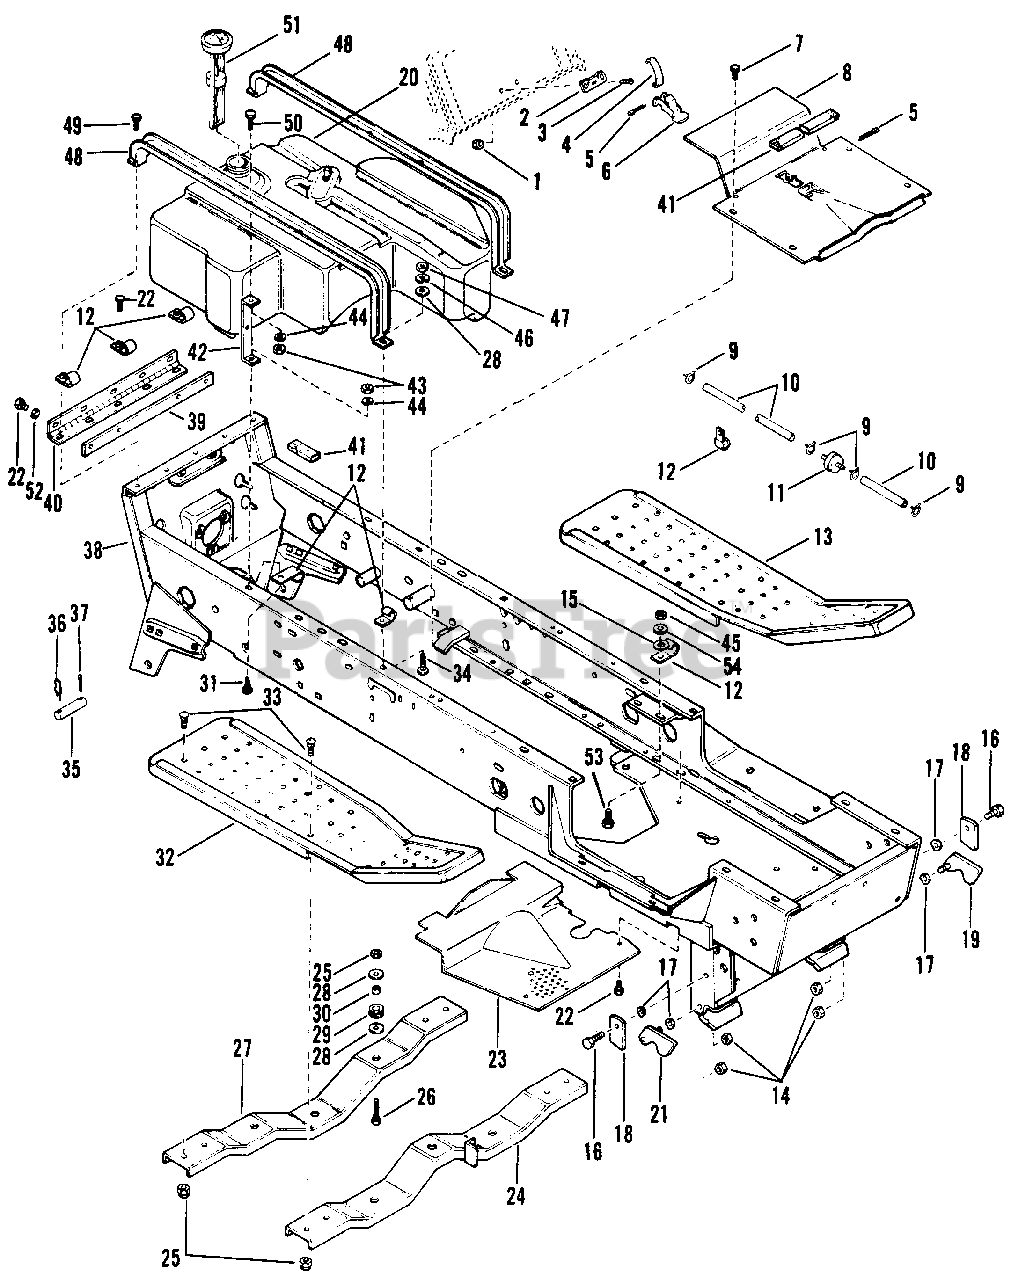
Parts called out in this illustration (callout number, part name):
1	Nut, Lock 10-24 Twin Whiz
2	Catch
3	Screw, Mach. 10-24 x .50 PHD
4	Spring, Deck Latch
5	Pin, Cotter .125 x 1.25
6	Lever, Deck Latch
7	Taptite, 1/4-20 x .375 HWH
8	Plate, Floor
9	Hose Clamp
10	Line, Fuel
11	Fuel Filter
12	Clip
13	L.H. Running Board
14	Nut, Lock 3/8-16
15	Washer, Flat .438 x 1.000 x .083
16	Bolt, Hex 3/8-16 x 1.00
17	Spring Washer
18	Lock Stop
19	Latch, L.H.
20	Gas Tank Assembly
21	Latch, R.H.
22	Bolt, Hex 5/16-18 x .50
23	Screen
24	Front Channel
25	Nut, Lock 5/16-18
26	Bolt, Hex 5/16-18 x 1.25
27	Rear Channel
28	Washer, Flat .406 x .812 x .065
29	Grommet
30	Spacer
31	Bolt, 1/4-20 x .75 Rd Hd Sq Nk
32	R.H. Running Board
33	Bolt, 5/16-18 x .625 Rd Hd Sq Nk
34	Bolt, Carriage 5/16-18 x .75
35	Pin
36	Pin, Hair
37	Pin, Cotter .125 x 1.00
38	Main Frame, Twin
39	Deck Mounting Strap
40	Hinge
41	Tape, Foam
42	Support
43	Nut, Hex 1/4-20
44	Washer, Lock 1/4 Reg.
45	Nut, Hex 3/8-16
46	Washer, Lock 5/16 SP
47	Nut, Hex 5/16-18
48	Channel
49	Taptite, 5/16-18 x .75 HWH
50	Screw, 1/4-20 x .75 Torx Slotted Ph Pl
51	Gas Gauge and Cap
52	Washer, Flat .375 x .734 x .065
53	Bolt, 3/8-16 x 1.00 Rd Hd Sq Nk
54	Washer, Lock 3/8 Reg.
NS	Floor Plate Decal
NS	Fan Decal
NS	Lift Selector Decal
NS	Chain Warning Decal
NS	Brake Decal
NS	Decal, America
